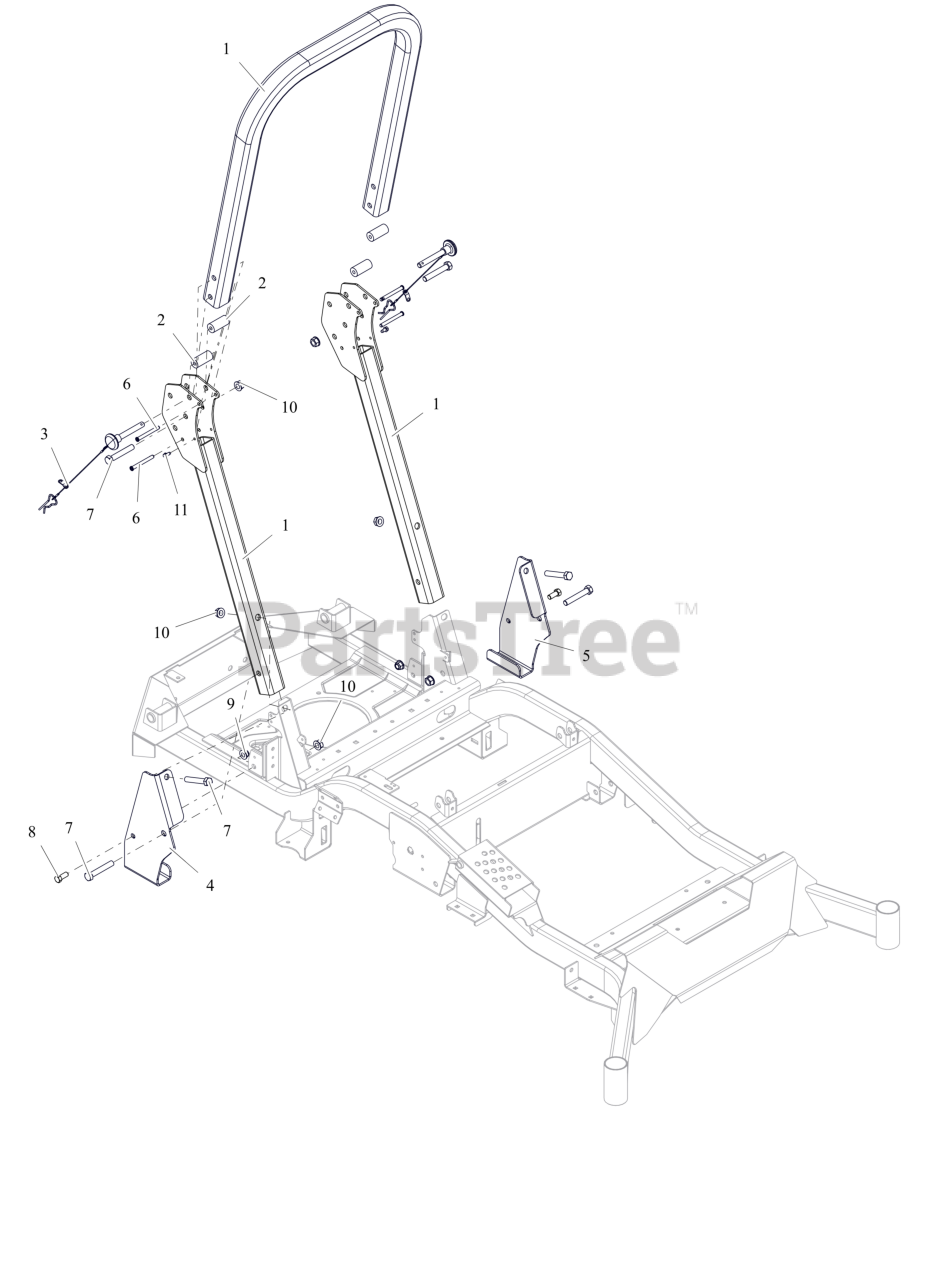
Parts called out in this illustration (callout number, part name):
1	ROPS,PROTURN Z REPLACEMENT-TALL
2	BUMPER, ROPS ANTI-VIBRATION
3	PIN, ROPS W/LANYARD
4	BRKT, ROPS SUPPORT - RH
5	BRKT, ROPS SUPPORT -LH
6	PIN, SLIC .312 X 2.57
7	BLT, HEX .50-13X3.00 G5 ZCC
8	BLT, HEX .44-14X1.00 G5 ZCC
9	NUT, LK-NYL-FLG .44-14 GR5 ZC120
10	NUT-LK-CTR-FLG .500-13 GG ZCC
11	SCR-TAP .25-20X.50 HWH ZCC
